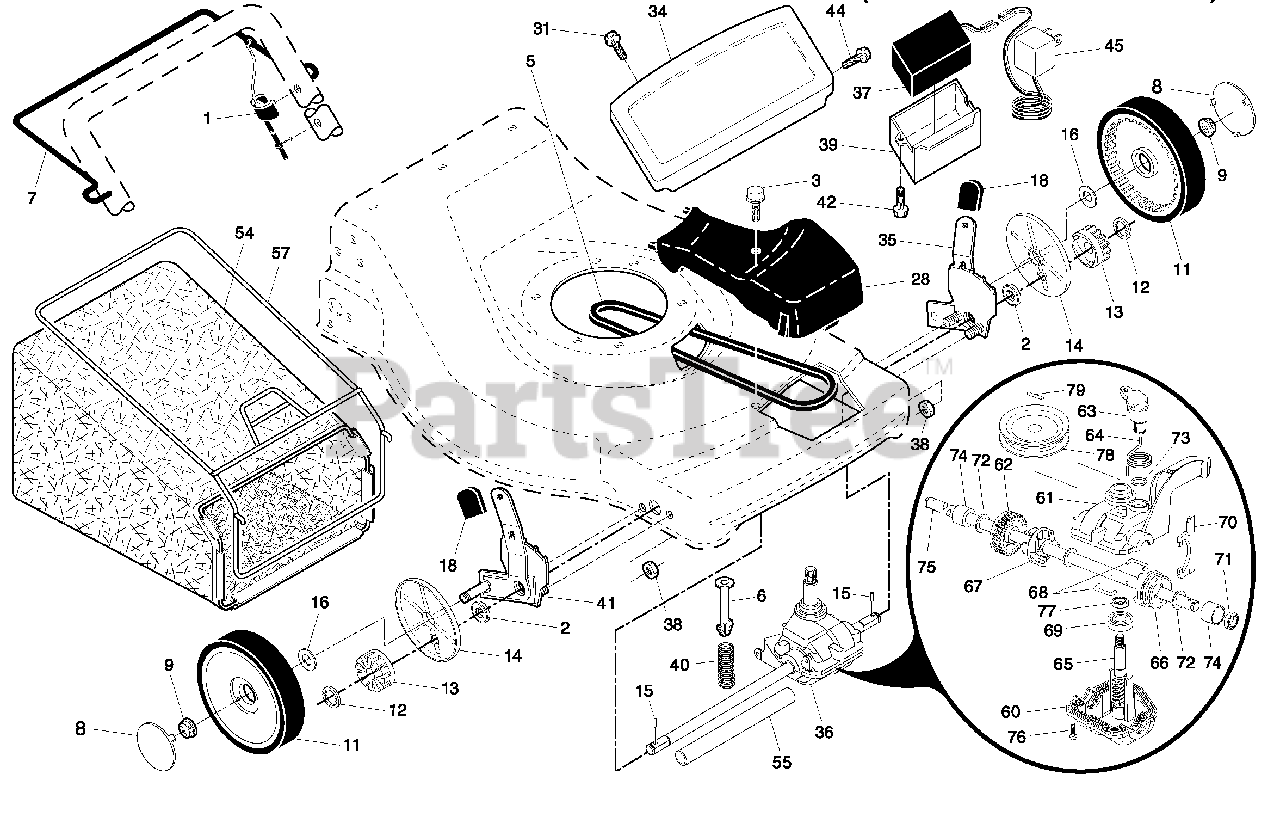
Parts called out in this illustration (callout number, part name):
1	Drive Control Assembly
2	Bearing, Wheel Adjuster
3	Pan Head Tapping Screw #10-24 x 2-3/4
6	Retainer, Spring
7	Bar, Drive Control
8	Hubcap
9	Locknut, Hex
11	Wheel & Tire Assembly, Front
12	E-Ring
13	Pinion
14	Dust Cover
15	Pawl, Drive
16	Washer, Flat 3/8
18	Selector Knob
28	Drive Cover
31	Screw, Trimplate
34	Trimplate
35	Kit, Wheel Adjuster, LH
36	Gear Case Assembly, Complete
37	Battery
38	Locknut 1/4-20
39	Battery Box
40	Spring
41	Kit, Wheel Adjuster, RH
42	Screw, Battery Box
44	Screw, Trimplate
45	Charger, Battery
54	Grassbag Assembly
55	Driveshaft Cover
57	Frame, Grassbag
60	Case, Lower
61	Case, Upper
62	Gear, 27 Teeth
63	Lever, Clutch
64	Spring, Return
65	Shaft, Input
66	Dog, Movable
67	Dog, Fixed
68	Wire, Formed
69	Bearing, Ball
70	Fork, Shift
71	Seal, Output Shaft
72	Washer
73	Seal, Case
74	Bushing
75	Shaft, Output
76	Screw
77	Seal, Input Shaft
78	Pulley, Drive
79	Pin, Retainer
